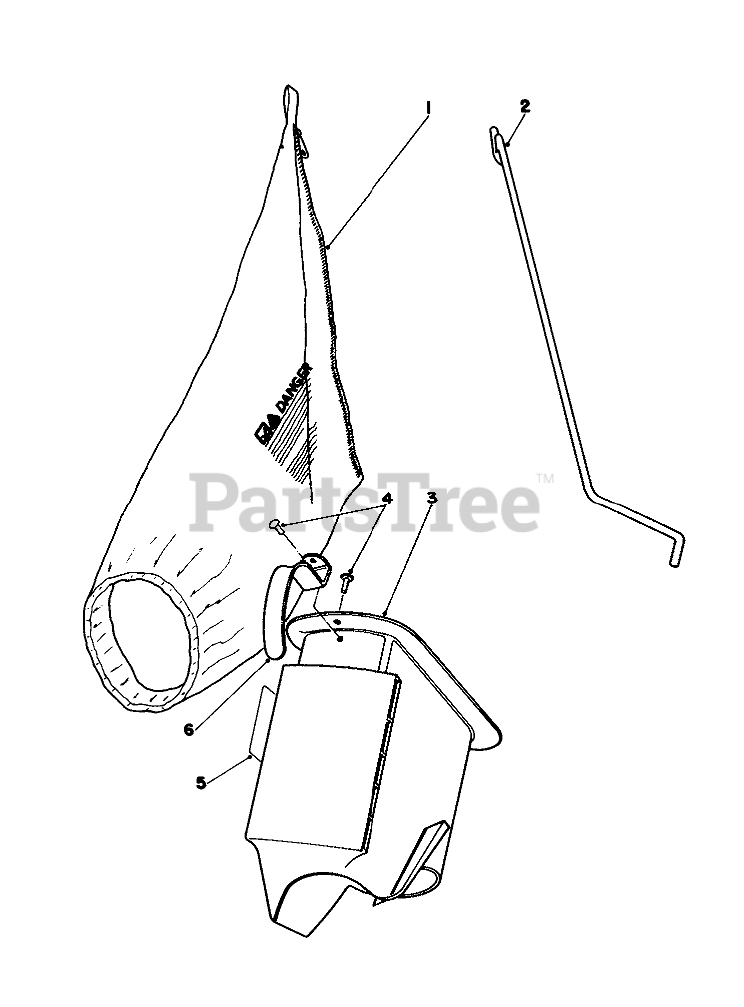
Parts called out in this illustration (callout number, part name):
1	BAG REPLACMNT44-0540
2	BAG ROD
3	Grass Chute (Incl. Ref. #4 & 6)
4	RIVET 3/16 X 7/16
5	BAG CHUTE DECAL
6	HANDLE-GRASS CHUTE
